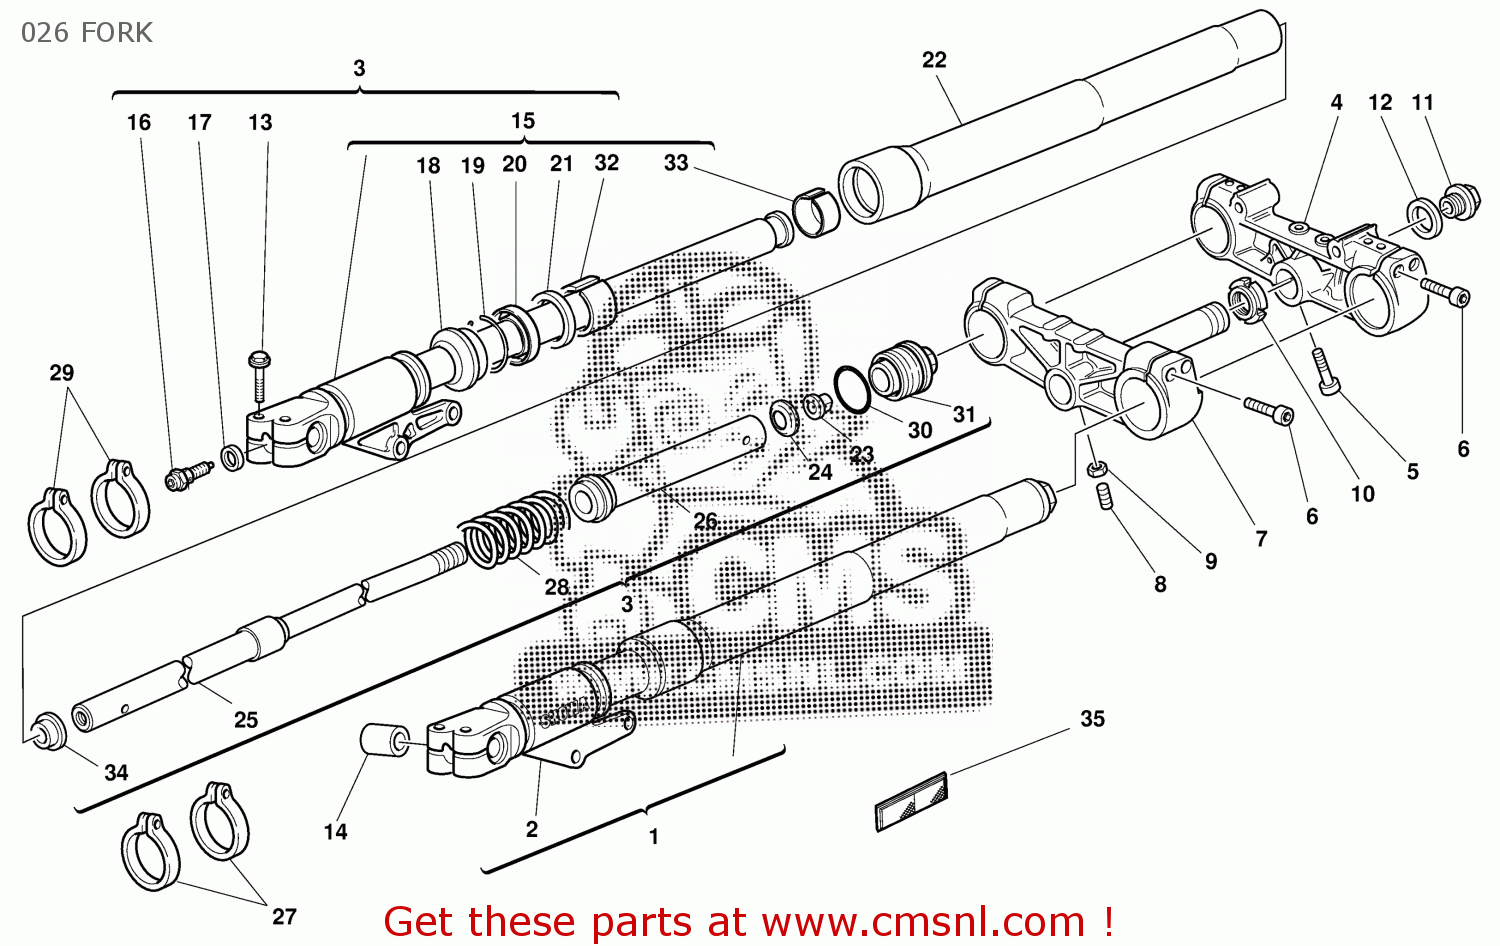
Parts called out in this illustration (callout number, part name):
1	FORK LEG ASSY, LEFT
2	COMPLETE LEFT SLIDER
3	FORK LEG ASSY, RIGHT
4	STEERING HEAD
5	SCREW 8X30
6	SCREW TCEI M8X1.25X30
7	STEERING CROWN WITH PIN
8	SCREW, SPECIAL
9	NUT
10	RING NUT
11	PLUG
12	WASHER
13	SCREW TCEI M8X1.25X35
14	WHEEL SPINDLE BUSH
15	COMPLETE RIGHT SLIDER
16	SCREW
17	WASHER
18	DUST COVER
19	SPRING RING
20	SEAL OIL, FORK
21	STOP RING
22	FORK OUTER TUBE
23	NUT
24	SPRING SEAT STOP
25	DAMPER PIPE
26	SPRING COLLAR
27	CLAMP, LH
28	FORK SPRING
29	CLAMP, RH
30	O-RING
31	SLEEVE PLUG
32	BUSH
33	BUSH
34	CENTERING RING
35	REFLECTOR, SIDE
